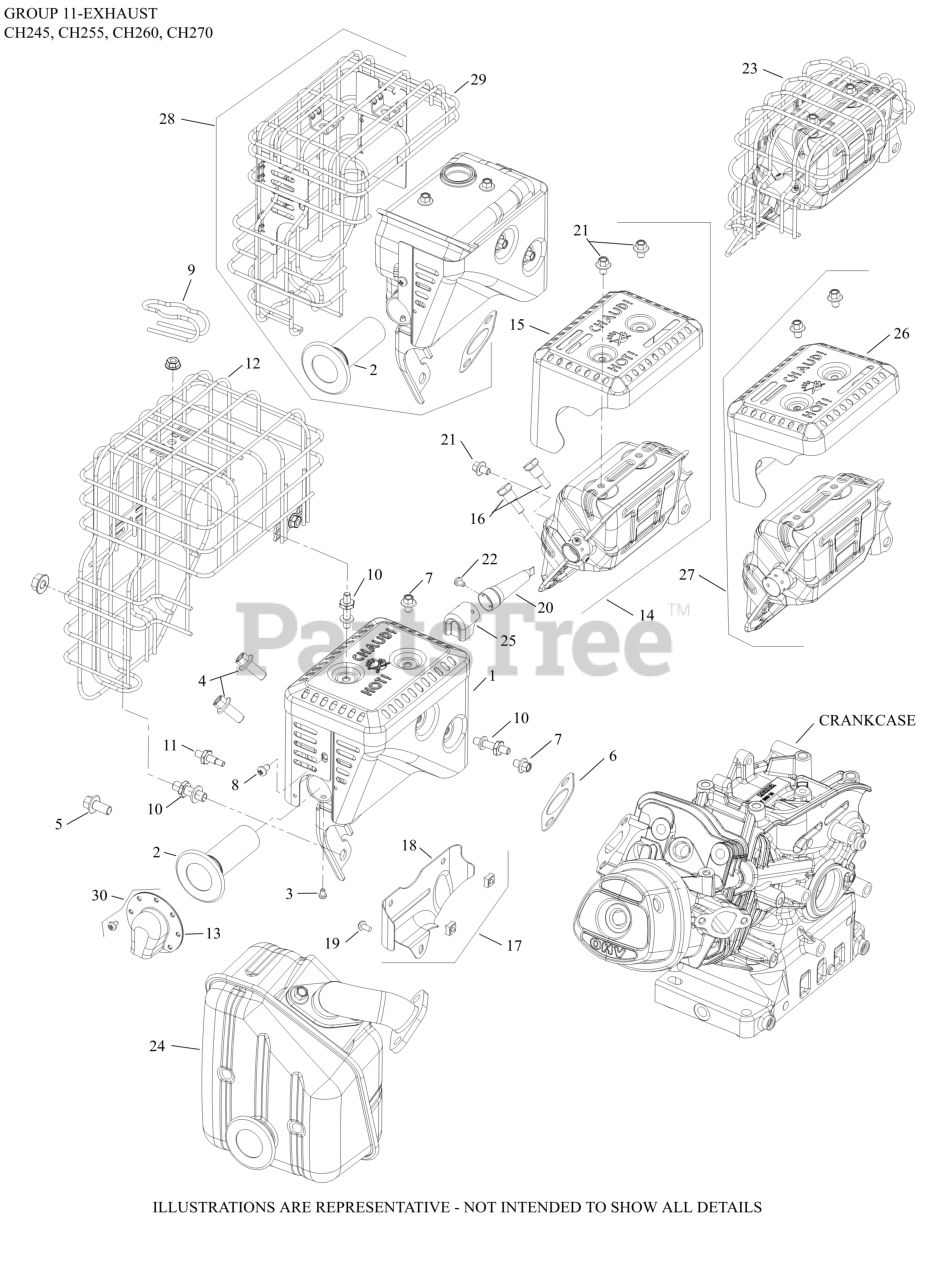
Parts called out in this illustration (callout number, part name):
3	SCREW, SPARK ARRESTOR
14	MUFFLER, ASSEMBLY
15	KIT, MUFFLER GUARD
16	SCREW, SHOULDER
20	SPARK ARRESTOR, ASSEMBLY
21	SCREW, M6 X 8 HEX FLANGE HEAD
32	GASKET, MUFFLER
